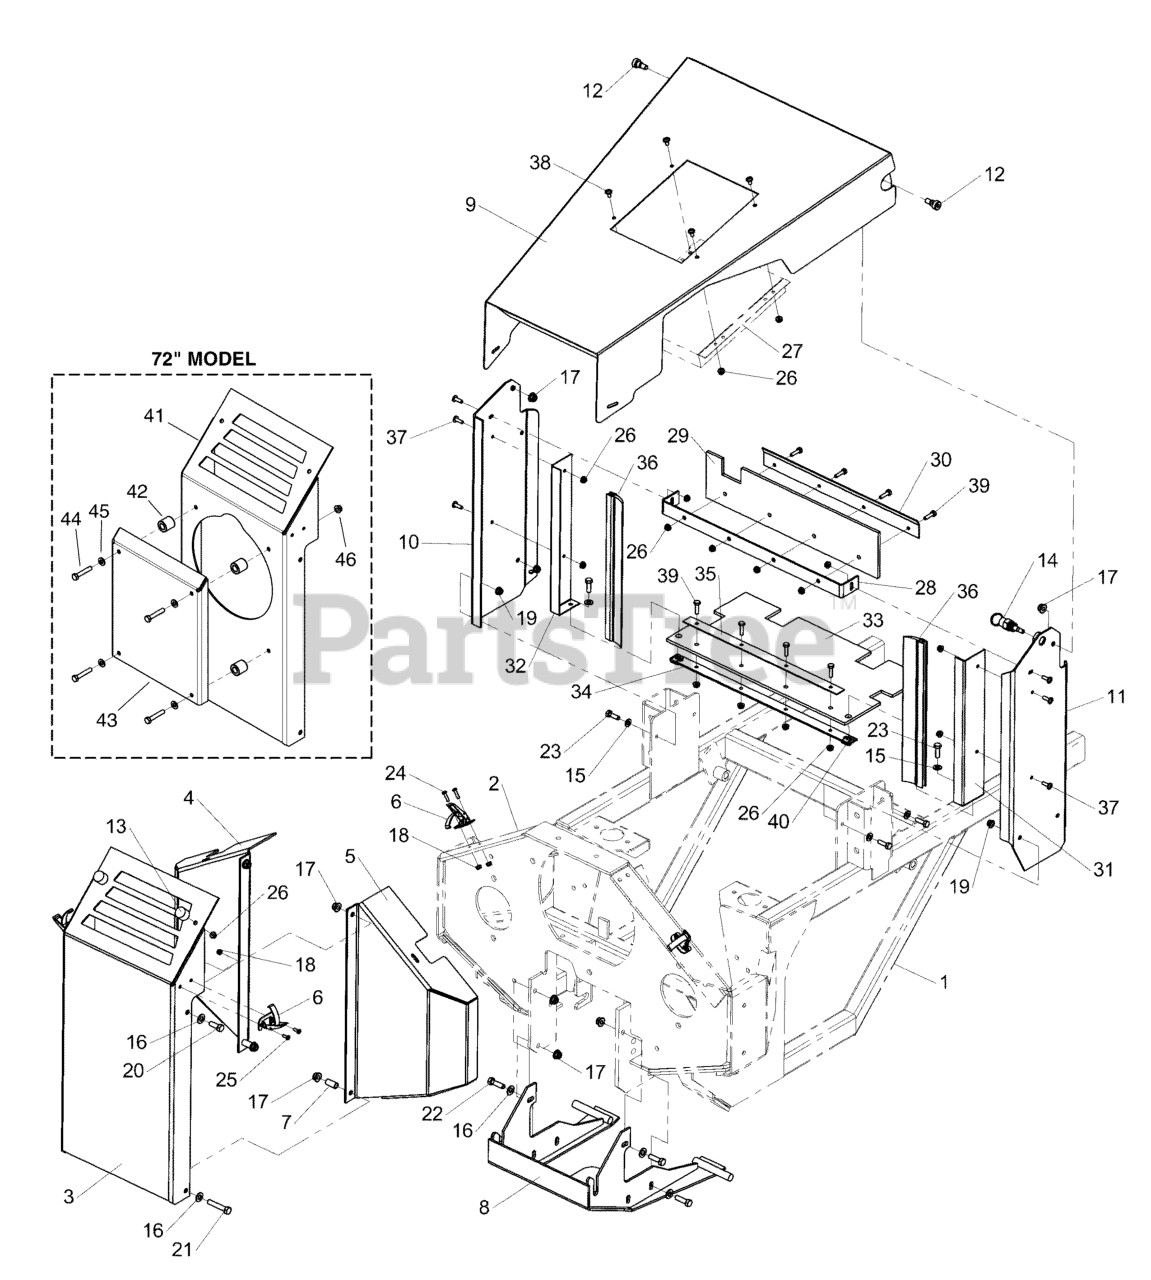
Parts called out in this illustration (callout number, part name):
1	MAIN FRAME
2	PUMP PLATE
3	BUMPER, CENTER
4	BUMPER SIDE, LH
5	BUMPER SIDE, RH
6	HOOD LATCH
7	SPACER, .38 X .50 X 1.00
8	SKID PLATE
10	SHROUD UPRIGHT, LH
11	SHROUD UPRIGHT, RH
12	SHOULDER BOLT, 1/2" X 3/8"
13	RUBBER BUMPER
14	LATCH PIN
15	WASHER, 5/16" SAE
16	WASHER, 3/8 SAE
17	NUT, 3/8-16 Hex Nylock Flange
18	NUT, #10-24 Hex Nylon Lock
19	NUT, 5/16-18 Hex Nylock Flange
20	BOLT, 3/8-16 X 1" GD5 CZ
21	BOLT, 3/8-16 X 2, GD5, CZ
22	BOLT, 3/8-16 X 1-1/4" GD5 CZ
23	BOLT, 5/16-18 X 1"
24	SCREW, #10-24 X 3/4"
25	SCREW, #10-24 x 1/2"
26	NUT, 1/4-20 Hex Nylock Flange
27	OIL COOLER
28	BAR, HOOD SUPPORT
29	RUBBER, RADIATOR FLAP
30	BAR, SUPPORT RADIATOR FLAP
31	SUPPORT, SCREEN RH
32	SUPPORT, SCREEN LH
33	RUBBER, FLAP BOTTOM
34	BAR, RUBBER SUPPORT BOTTOM
35	SUPPORT, RUBBER
36	WIPER SEAL, 14-3/8"
38	SCREW, Allen Head, 1/4-20 x 1/2
39	BOLT, 1/4-20 X 1" GD5 CZ
40	BODY CLIP, 5/16-18-7GA MATERIAL
41	BUMPER, CENTER
42	SPACER, .52 X 1.00 X 1.00
43	CLUTCH COVER PLATE
44	BOLT, 5/16-18 X 1-3/4"
45	WASHER, 5/16" SAE
46	NUT, 5/16-18 Hex Nylock Flange
